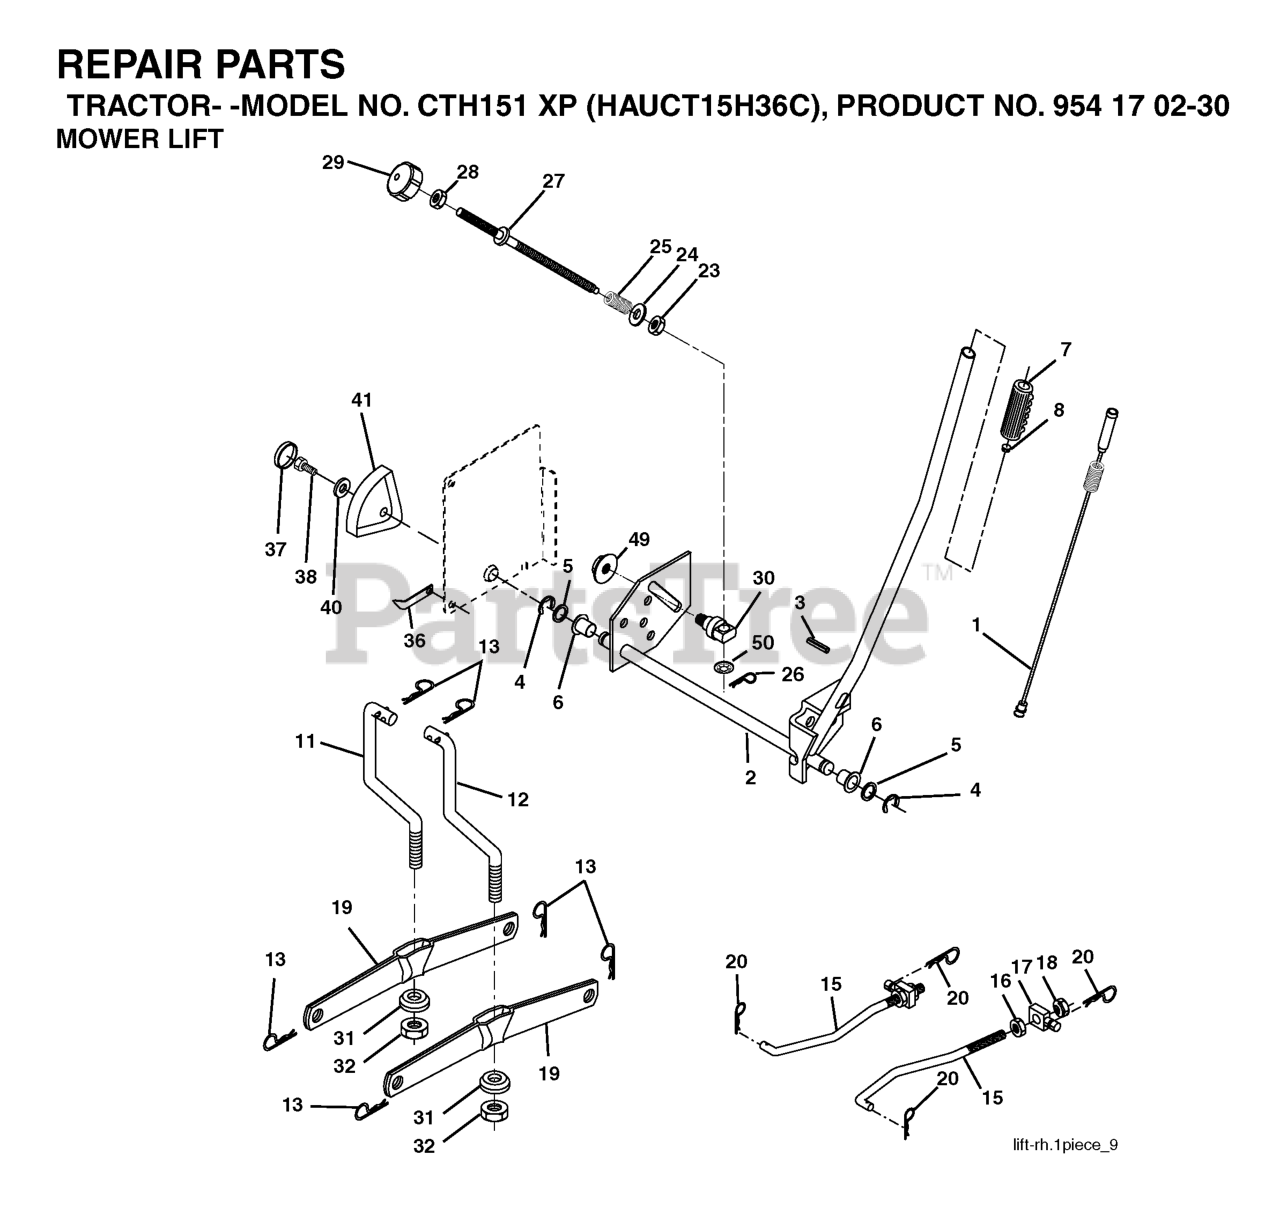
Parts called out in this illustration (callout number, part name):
1	WIRE.ASM.INNER.SP
2	SHAFT.ASM.LIFT.RH.INF
3	PIN.GROOVE.5/16
4	RETAINING RING LT
6	BEARING.NYLON
7	GRIP HANDLE
8	PLUNGER BUT KIT
11	LINK
12	LINK
13	RETAINER-SPRNG RB
15	LINK.SUSPENSION.FRONT
16	NUT.HEX.JAM.1/2-13
18	NUT.LK.W/WSH.1/2.
19	ARM.REAR.SUSPENSION
20	SPRING RETAINER
25	SPRING.COMP.INF.H
26	RETAINER CLIP
27	ROD.LIFT.ADJUSTABLE
28	NUT
29	KNOB INF 3/8-16
31	BEARING.PIVOT.LIFT
32	NUT CROWNLOCK 3/8-24
36	POINTER, HEIGHT INDICATOR(2 2)
38	SCREW 5/16-18X1
41	HEIGHT INDICATOR
49	NUT
50	NUT PUSH M
